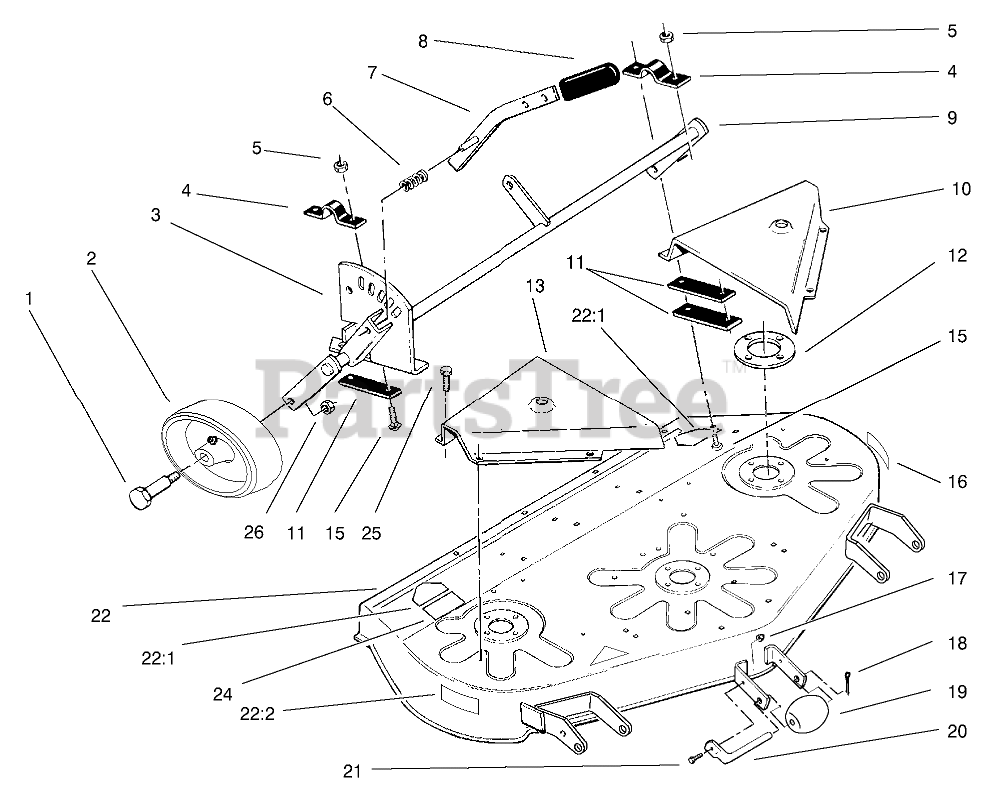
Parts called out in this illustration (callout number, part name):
1	BOLT-SHOULDER
2	WHEEL
3	Quadrant
4	CLAMP (BLACK)
5	NUT-LOCK, NI
6	SPRING-COMPRESSION
7	WLDMT-LEVER (RED)
9	WDT-GAGE WHEL (RED)
10	COVER BELT, LH
11	STRAP 3/16 (BLACK)
12	PLATE-SPINDLE
13	COVER-BELT, RH
15	BOLT-CARR
17	NUT-LOCK, NI
18	PIN-COTTER
19	ROLLER
20	Shaft-Roller
21	SCREW-HH
22	ASM DECK/DECAL
24	DECAL-HEIGHT & BELT
25	SCREW-HWH
26	NUT-HEX
